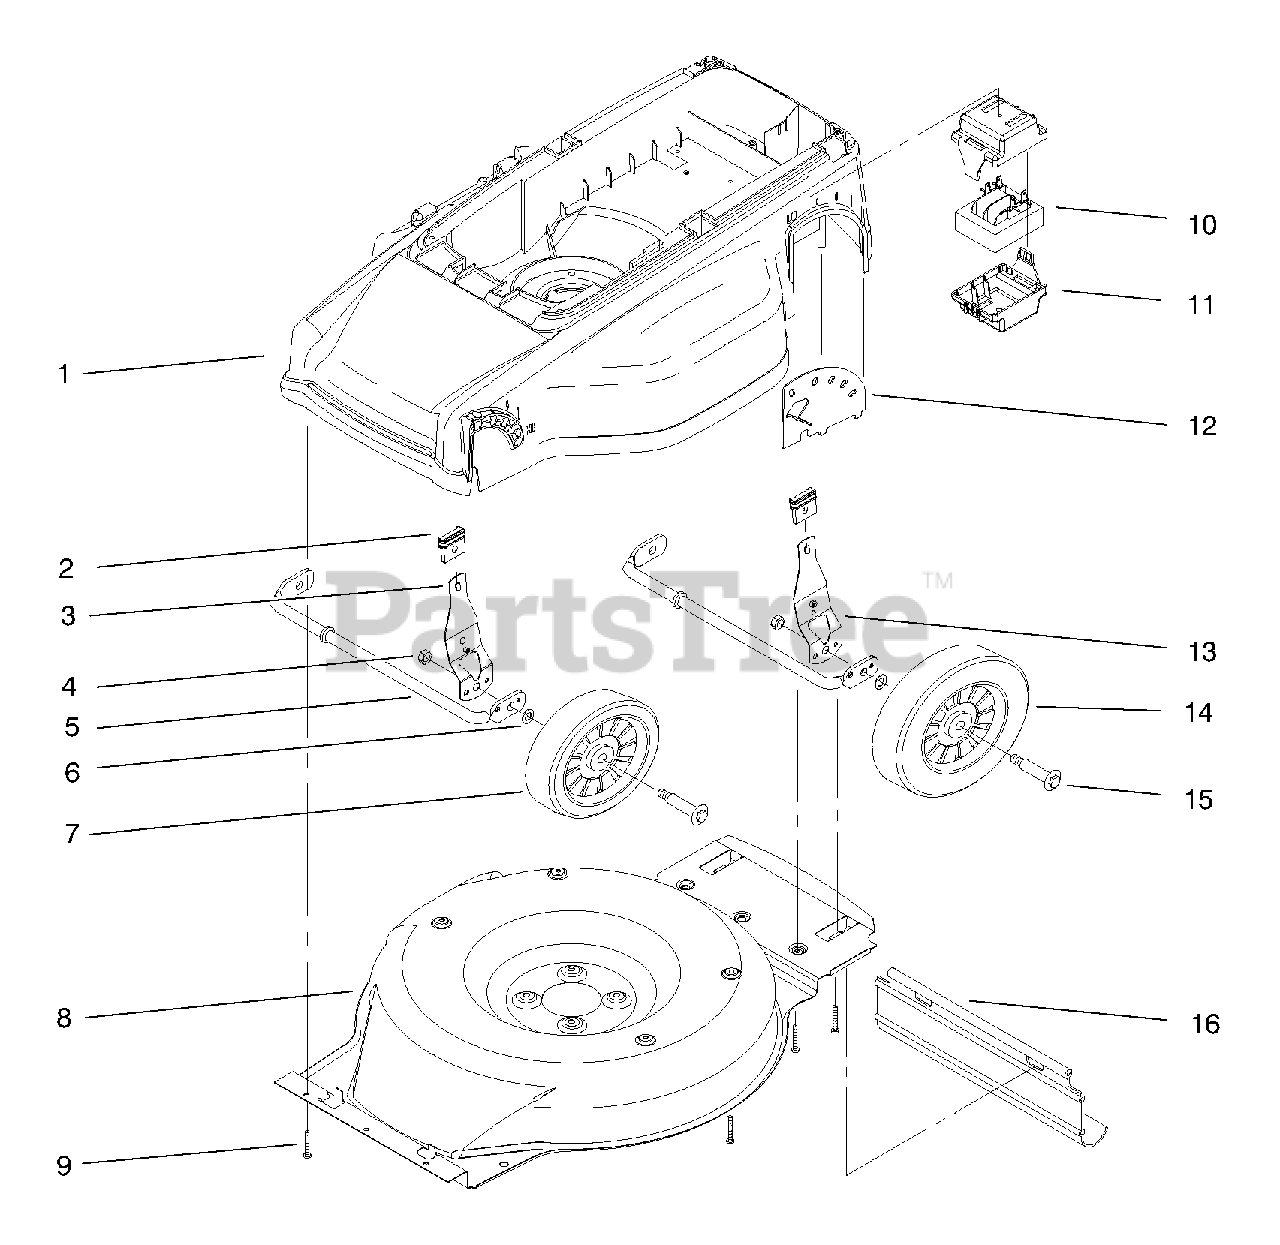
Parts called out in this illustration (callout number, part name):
2	Knob-Height Adjust
3	ASM-Front HOC Lever
4	Nut-Lock
7	ASM-Wheel
8	ASM-Liner
9	Screw-PPH
10	Transformer 36 Volt
11	Housing-Transformer
12	Plate-HOC
13	ASM-Rear HOC Lever
14	ASM-Wheel
15	Bolt-Shoulder
16	Trailing Shield
